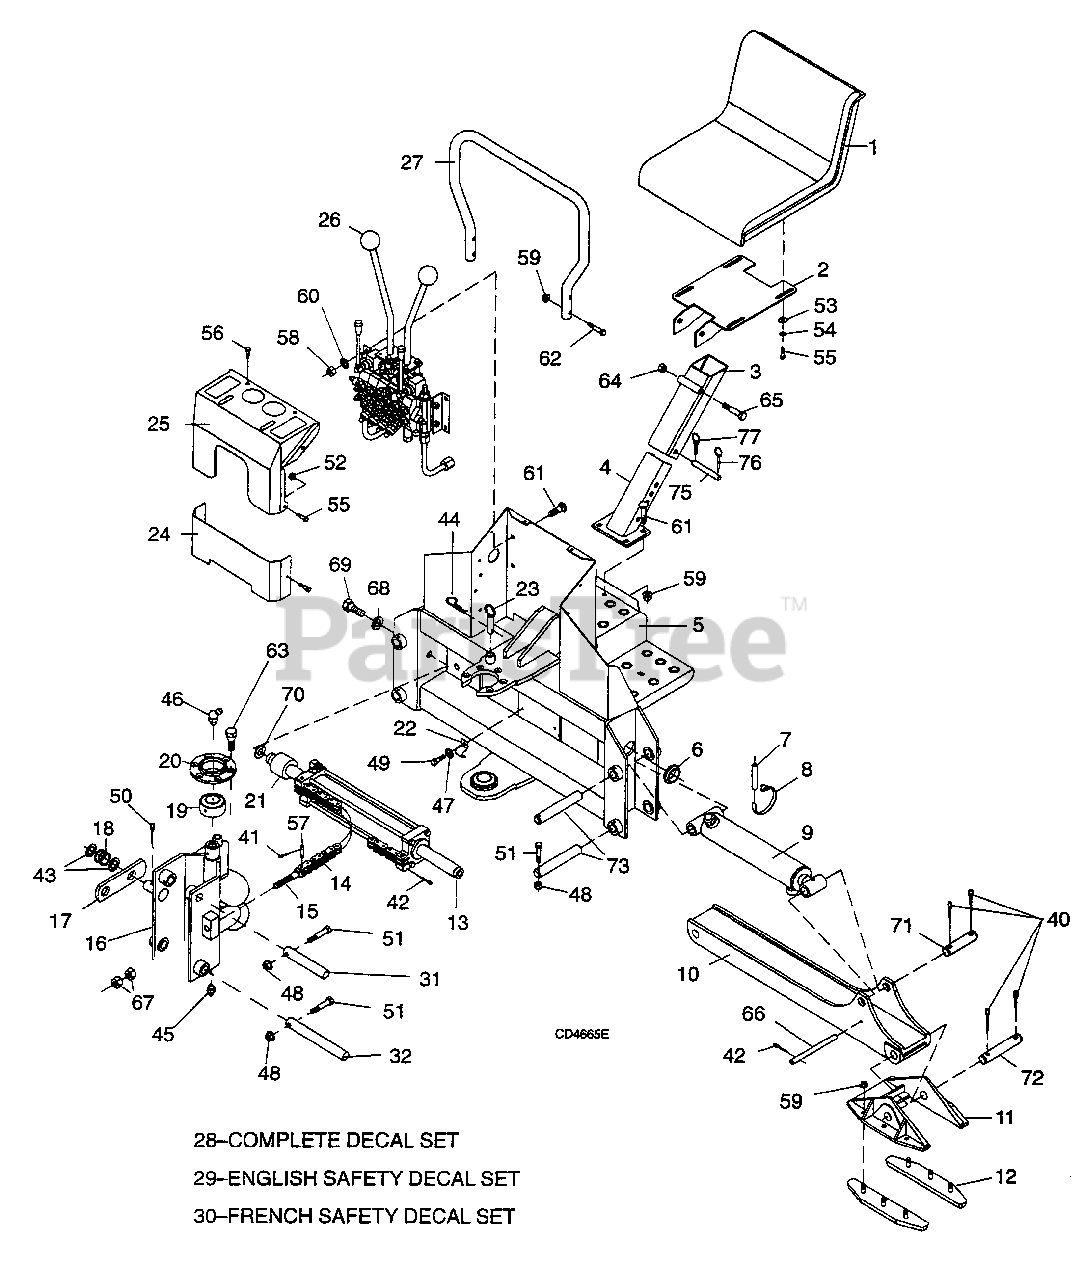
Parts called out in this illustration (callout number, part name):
1	High back seat
2	Seat bracket
3	Upper seat support
4	Lower seat support
5	Main frame
6	Rubber grommet
7	Hose protector shield
8	2-1/2" - 3-1/2" Hose clamp
9	Hydraulic cylinder, double-acting 2-1/2 x 11
10	Machined stabilizer arm
11	Machined stabilizer pad
12	Stabilizer rubber pad
13	Hydraulic cylinder, double-acting, 2.50 x 10.63
14	Swing Chain
15	Chain tension bolt
16	Backhoe swing frame
17	Link - .38 x 2.0 x 7.1
18	Spring - Compression 1.19 x .07 x .627
19	1-1/2 ID Ball bushing
20	Cap weld assembly
21	Bumper - 1.25 x 2.25 x 1.75
22	Hose clamp
23	.62 x 3.31 Swing lock pin
24	11 GA x 5.13 x 12.9 Cover
25	Cub Cadet console cover
26	Valve and console assembly
27	1.05 x 13.3 x 15.5 Handle
28	Complete English decal set
29	English safety decal set
30	French safety decal set
31	Bar Dr 1.00 x 4.55 x 6.00
32	Bar Dr 1.00 x 7.30 x 7.69
40	3/16 x 1-1/2 Cotter pin
41	3/32 x 1/2 Cotter pin
42	3/32 x 1-1/2 Cotter pin
43	10 GA x 1 Bushing
44	3/16 Safety pin
45	1/4-28 Tapered thread grease fitting
46	45ø 1/4 Tapered thread grease fitting
47	1/4 Standard lockwasher
48	1/4 NC Hex locknut
49	1/4 NC x 3/4 Hex head cap screw GR5
50	1/4 x 1-1/2 Cotter pin
51	1/4 NC x 2-1/4 Hex head cap screw GR8
52	5/16 NC Flange locknut
53	5/16 Standard flat washer
54	5/16 Standard lockwasher
55	5/16 NC x 3/4 Hex head cap screw GR5
56	.31 x .75 Sheet metal screw
57	.312 x 1.45 Chain pin
58	3/8 NC Hex nut plated
59	3/8 NC Flange hex locknut
60	3/8 Standard lockwasher
61	3/8 NC x 1 Carriage bolt GR5
62	7/16 NF Hex locknut
63	7/16 NF x 1-1/4 Wheel bolt
64	1/2 NC Hex locknut
65	1/2 NC x 4 Hex head cap screw GR5
66	.50 x 4.45 Headless pin
67	5/8 NC Hex nut
68	3/4 Standard lockwasher
69	3/4 NC x 1-1/2 Hex head cap screw HT
70	13/16 x .010 Shim washer
71	1.0 x 3.80 Headless pin
72	1.0 x 5.84 Headless pin
73	1.00 x 5.92 x 6.31 Drilled bar
